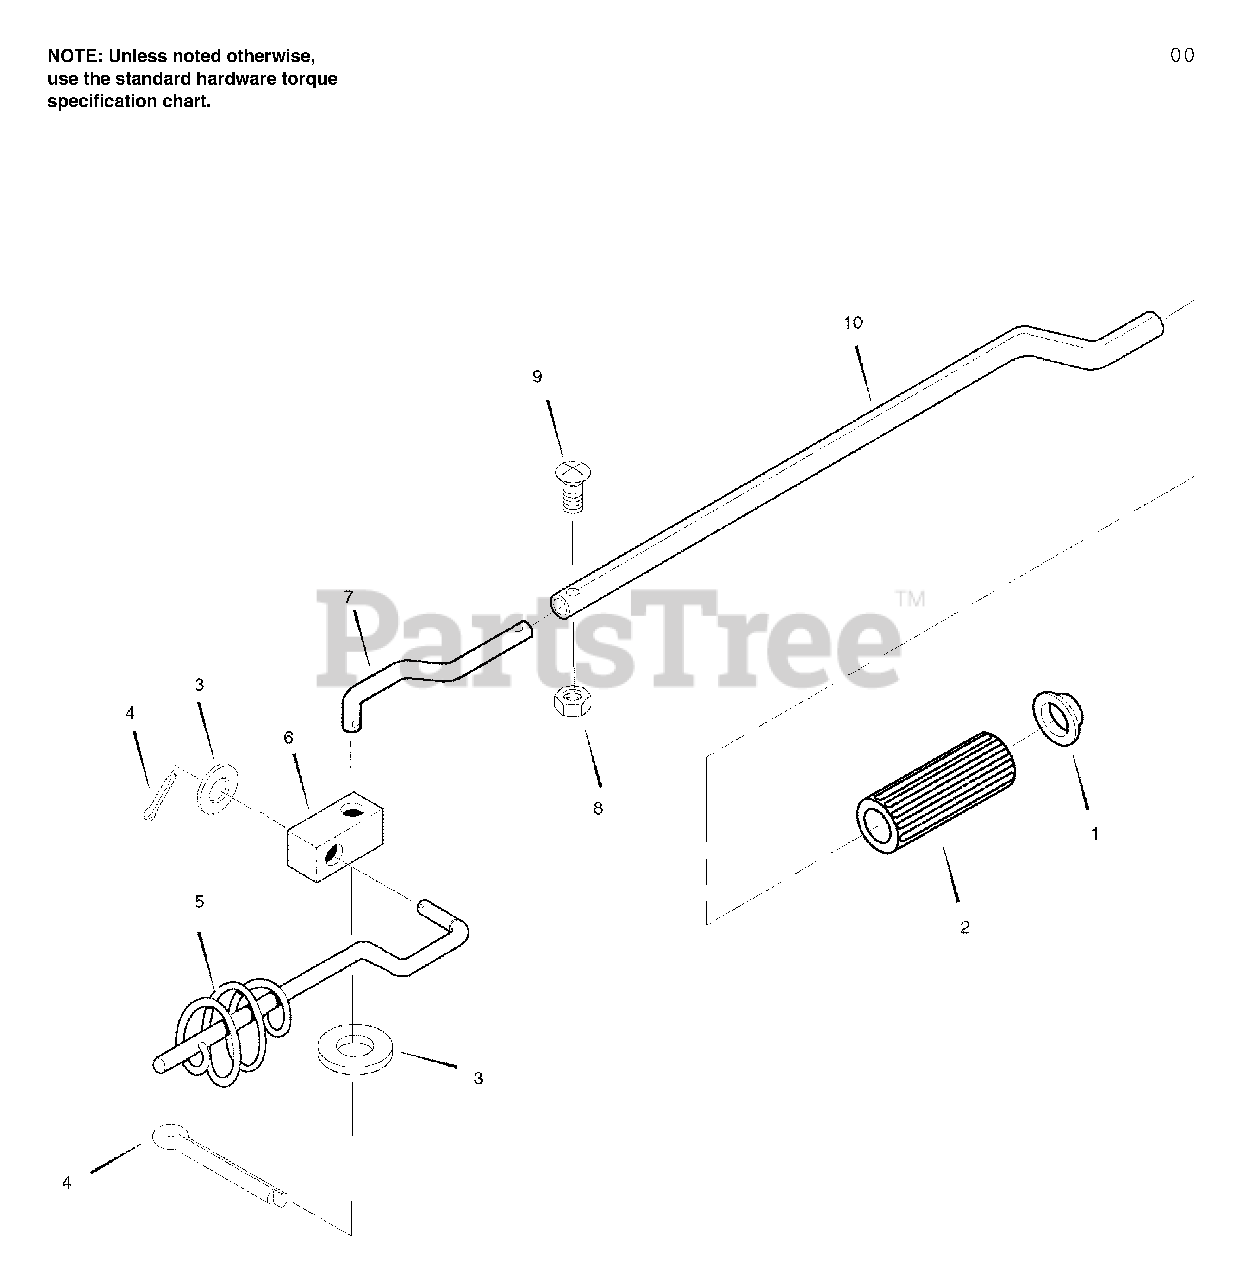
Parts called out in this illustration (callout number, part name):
2	KNOB, GRIP
3	WASHER, FLAT .400 x .75 x .02
4	PIN, COTTER
5	ROD, CHUTE CNTRL LWR
6	BLOCK, PIVOT
7	ROD, CHUTE CNTRL MID
8	NUT, LOCK 10-32
9	SCREW, 10-32 x .88
10	ROD, CHUTE UPPER
